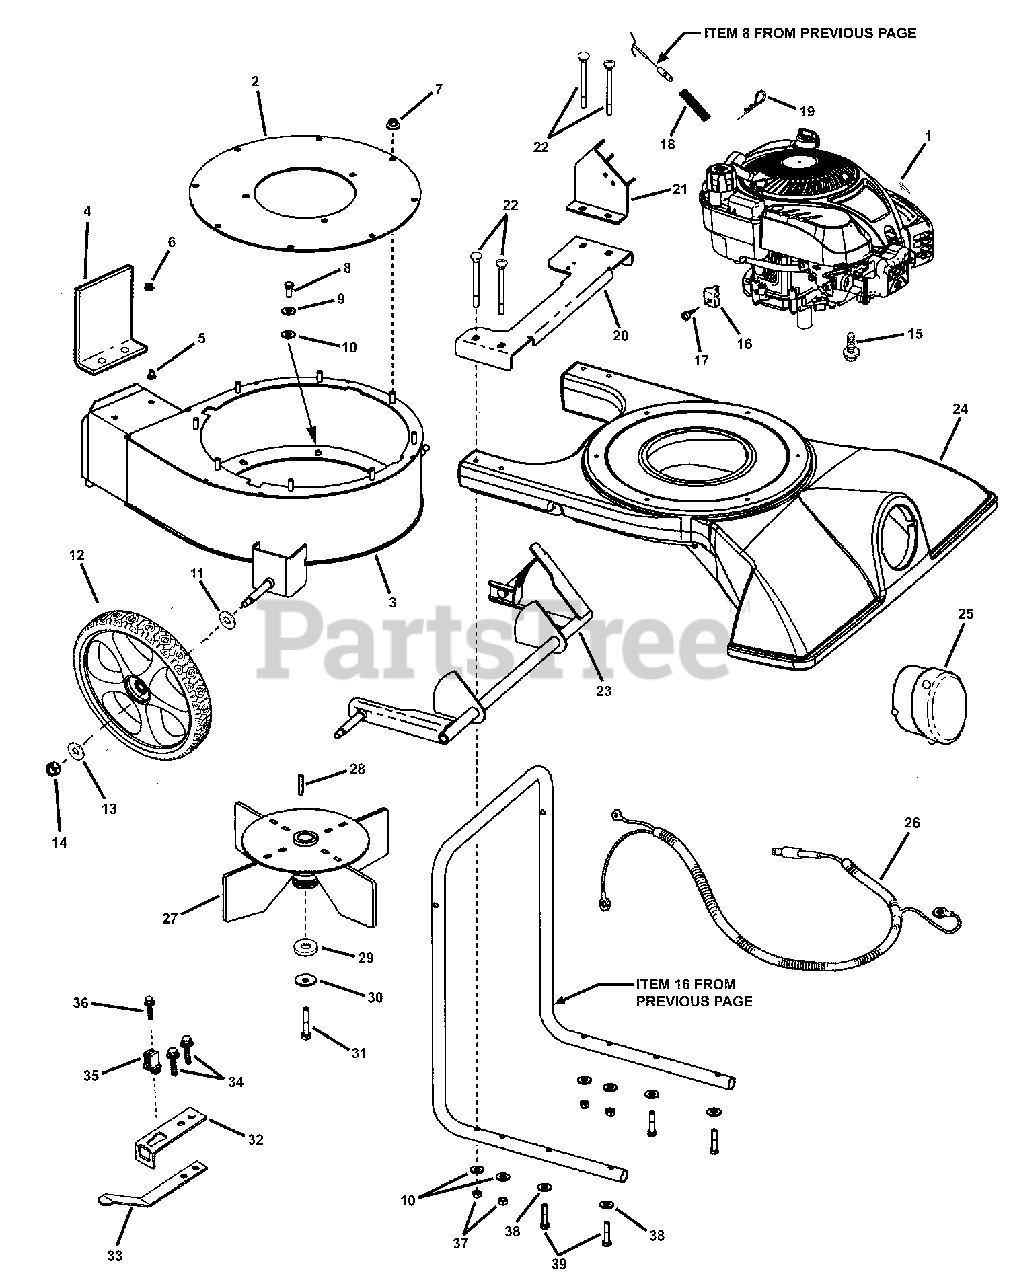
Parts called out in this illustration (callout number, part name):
2	PLATE, Engine Base Vacuum Universal
3	HOUSING ASSEMBLY, Upper
4	ASSEMBLY, Hinge Door
5	CARRIAGE BOLT, 1/4-20 x 1/2 Short Neck, GR5
6	NUT, 1/4-20 Hex Flange Lock
7	NUT, 5/16-18 Hex Flange Lock, GR5
8	CAPSCREW, 5/16-18 x 3/4 Hex Head, GR5
9	WASHER, 5/16 Split Lock
10	WASHER, 5/16 Flat
11	WASHER, 1/2 Wave
12	WHEEL ASSEMBLY, 14.00 x 2
13	WASHER, 3/8 SAE Flat
14	NUT, 3/8-16 Nyloc
15	SCREW, 3/8-16 x 1 Hex Washer Self-Tap
16	CLAMP, Casing
17	SCREW, #10-32 x 5/8 Hex Head Self-Tap
18	SPRING, Compression
19	HAIRPIN, 29/32 Cotter
20	PLATE, Reinforcing
21	CABLE ANCHOR ASSEMBLY
22	CARRIAGE BOLT, 5/16-18 x 3-1/2 Short Neck, GR5
23	AXLE ASSEMBLY, Drag Link
24	HOUSING, Lower
25	PLUG, Hose Port
26	WIRE HARNESS, Interlock
28	KEY, 1/4 Square x 1-7/16 long
29	WASHER, .468 I.D. x 1-5/8 O.D. x 1/4 thick
30	WASHER,Cone
31	CAPSCREW, 3/8-24 x 2 Hex Head, GR5
32	BRACKET, Interlock
33	SPRING, Interlock
34	CAPSCREW, 1/4-20 x 1/2 Hex Washer Self-Tap
36	SCREW,# 8-18 x 3/4 Sheet Metal
37	NUT, 5/16-18 Hex Nyloc
38	WASHER, 5/16 Split Lock
39	CAPSCREW, 5/16-18 x 1-1/2 Hex Head, GR5
